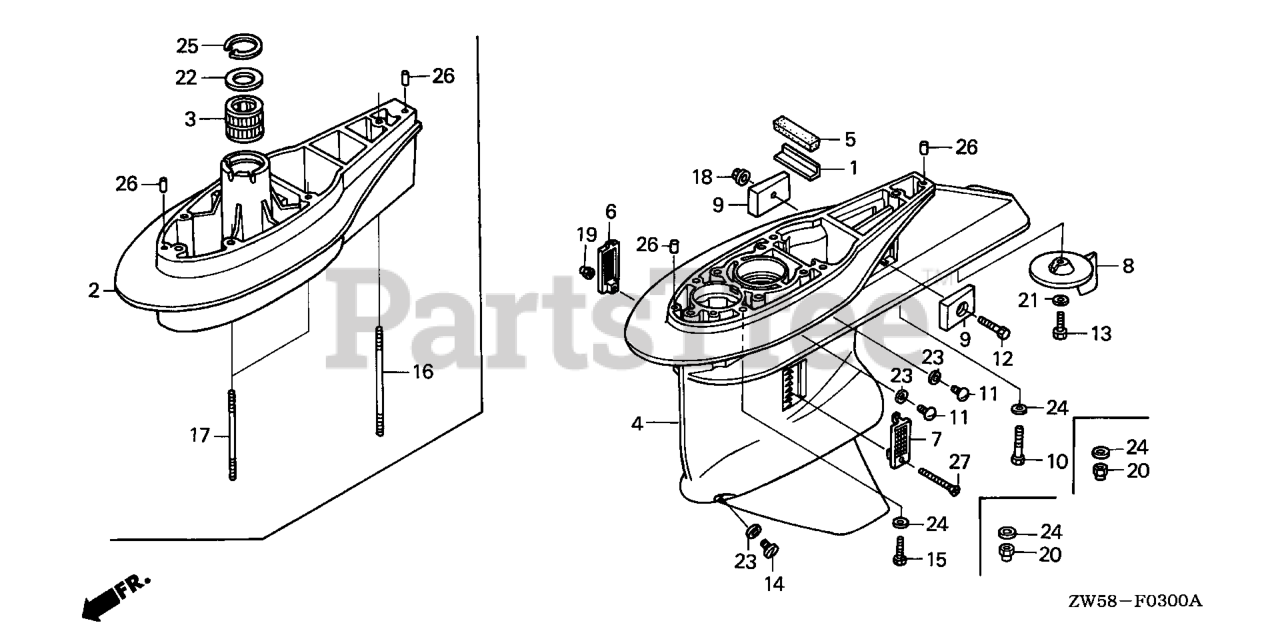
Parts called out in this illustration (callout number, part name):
1	PLATE, RUBBER SETTING
4	CASE, GEAR *NH282MU* (OYSTER SILVER METALLIC-U)
5	GROMMET, GEAR CASE
6	SCREEN, R. WATER
7	SCREEN, L. WATER
8	TAB, TRIM *NH282MU* (OYSTER SILVER METALLIC-U)
9	METAL, ANODE
10	BOLT, HEX. (10X80)
11	BOLT, OIL CHECK
11	BOLT, OIL CHECK (8X8)
12	BOLT, HEX. (6X32)
13	BOLT, HEX. (8X25)
14	BOLT, DRAIN PLUG (8MM)
15	BOLT, HEX. (10X40)
18	NUT, SELF-LOCK (6MM)
19	NUT, SELF-LOCK (5MM)
21	WASHER, PLAIN (8MM)
23	WASHER, NYLON (8MM)
24	WASHER, PLAIN (10MM)
26	PIN, DOWEL (6X10)
27	SCREW, OVAL (5X45)
